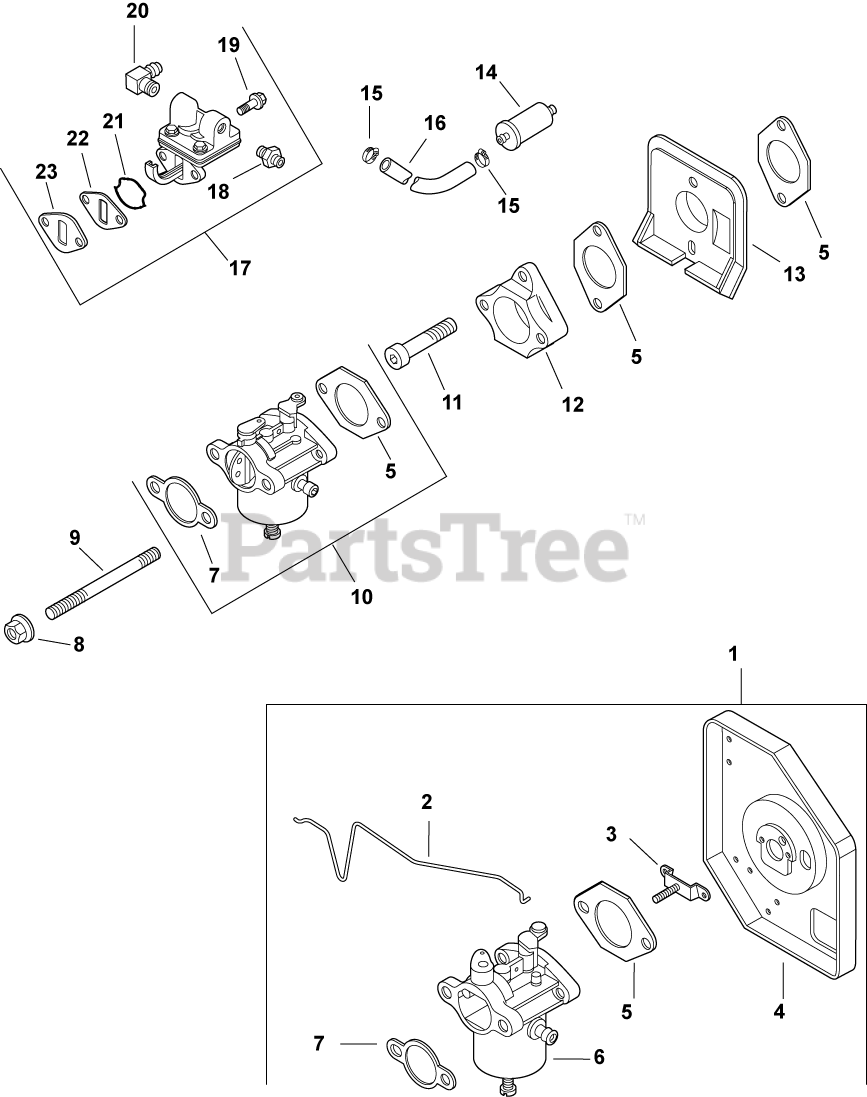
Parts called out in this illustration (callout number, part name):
1	KIT, CARB. RETROFIT
2	LINKAGE, CHOKE
3	BRACKET, AIR CLEANER
4	BASE, AIR CLEANER
5	GASKET, CARBURETOR
6	CARBURETOR W/GASEKTS - USE 12 853 139-S
7	GASKET, AIR CLEANER BASE
8	NUT, FLG M6X1.0
9	STUD,M6X1.0X116
10	KIT, CARBURETOR w/GASKETS
11	SCREW, SKT CAP M6X1.0X35
12	ADAPTER, CARBURETOR
13	DEFLECTOR, HEAT
14	FILTER, FUEL
15	CLAMP, HOSE (KM)-USE 25 237 31-S
16	LINE, FLEXIBLE FUEL
17	KIT, FUEL PUMP
18	KIT, STRAIGHT FITTING
19	SCREW, LBD SKT M6x1.0x20-(#25086403S)
20	CONNECTOR, 90 DEG. HOSE
21	O-RING, FUEL PUMP
22	SPACER, FUEL PUMP
23	GASKET, FUEL PUMP
